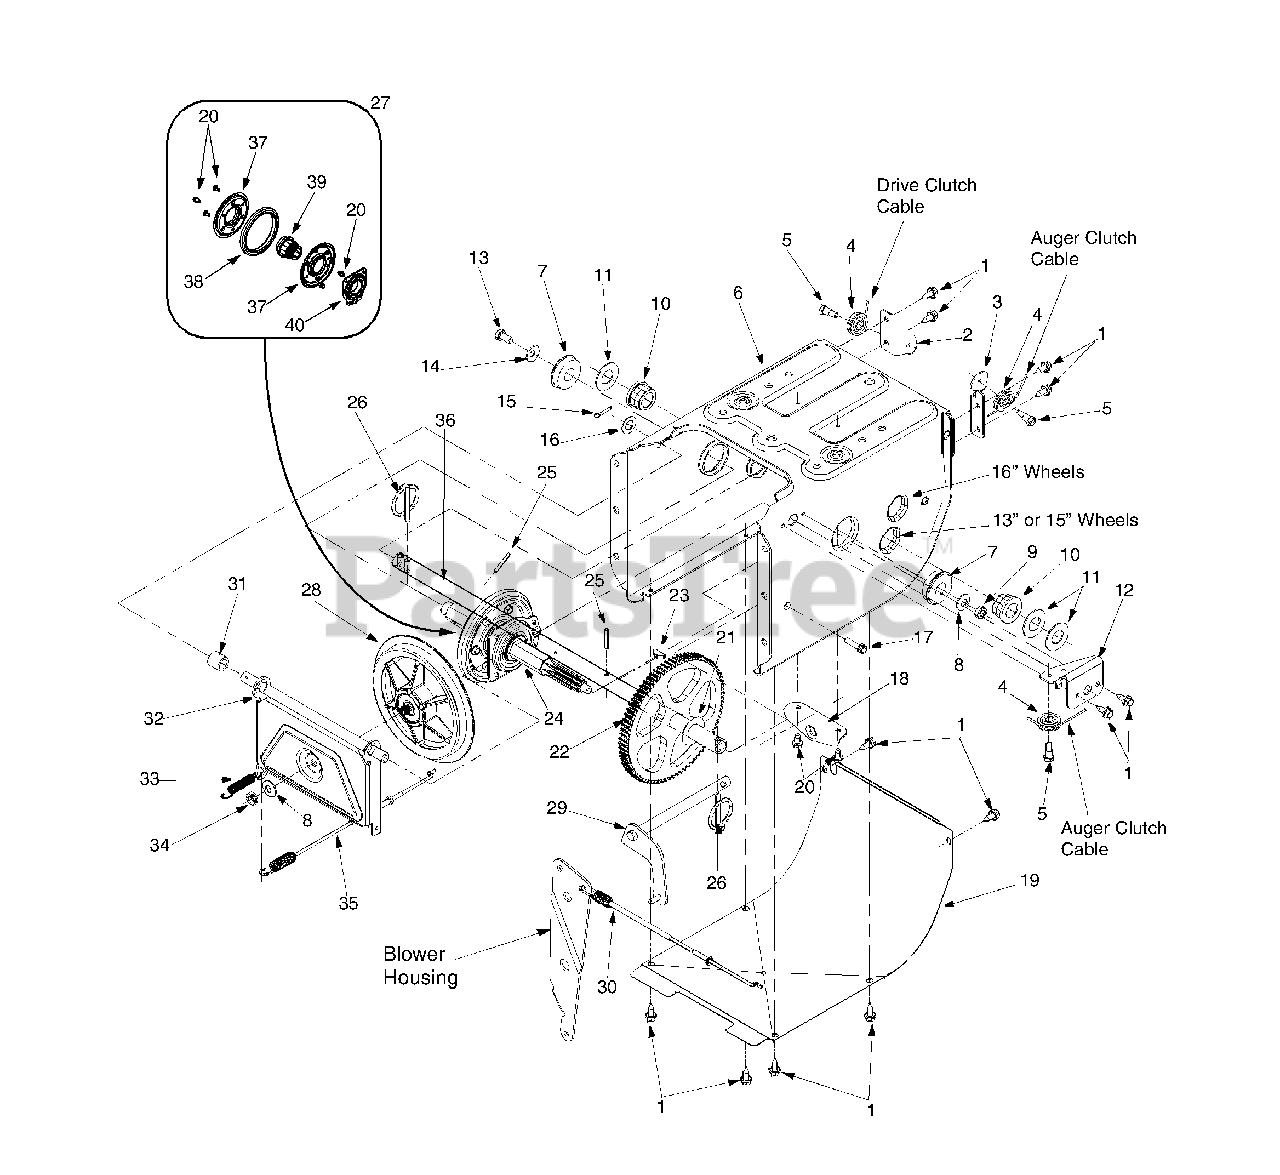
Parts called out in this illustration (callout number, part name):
1	Hex Screw
5	Hex Screw 1/4-28
8	Bell Washer
9	Lock Jam Nut
10	Hex Flange Bearing
11	Flat Washer
14	Bell Washer .340 ID x .872 OD
15	Cotter Pin
16	Flat Washer .536 ID x .930 OD
17	Hex Washer Screw 1/4-20
21	Flat Washer .760 ID x .50 OD
24	7-Tooth Shaft
25	Roll Pin
26	Klik Pin
27	Friction Wheel Assembly
28	Friction Disc Wheel
29	Wheel Shift Rod Assembly
30	Drive Cable
31	Spacer
34	Jam Nut 3/8-24
35	Drive Cable
36	Axle 13" Wheels
37	Friction Plate
38	Friction Wheel Rubber
39	Friction Wheel Hub
40	Friction Wheel Bearing
